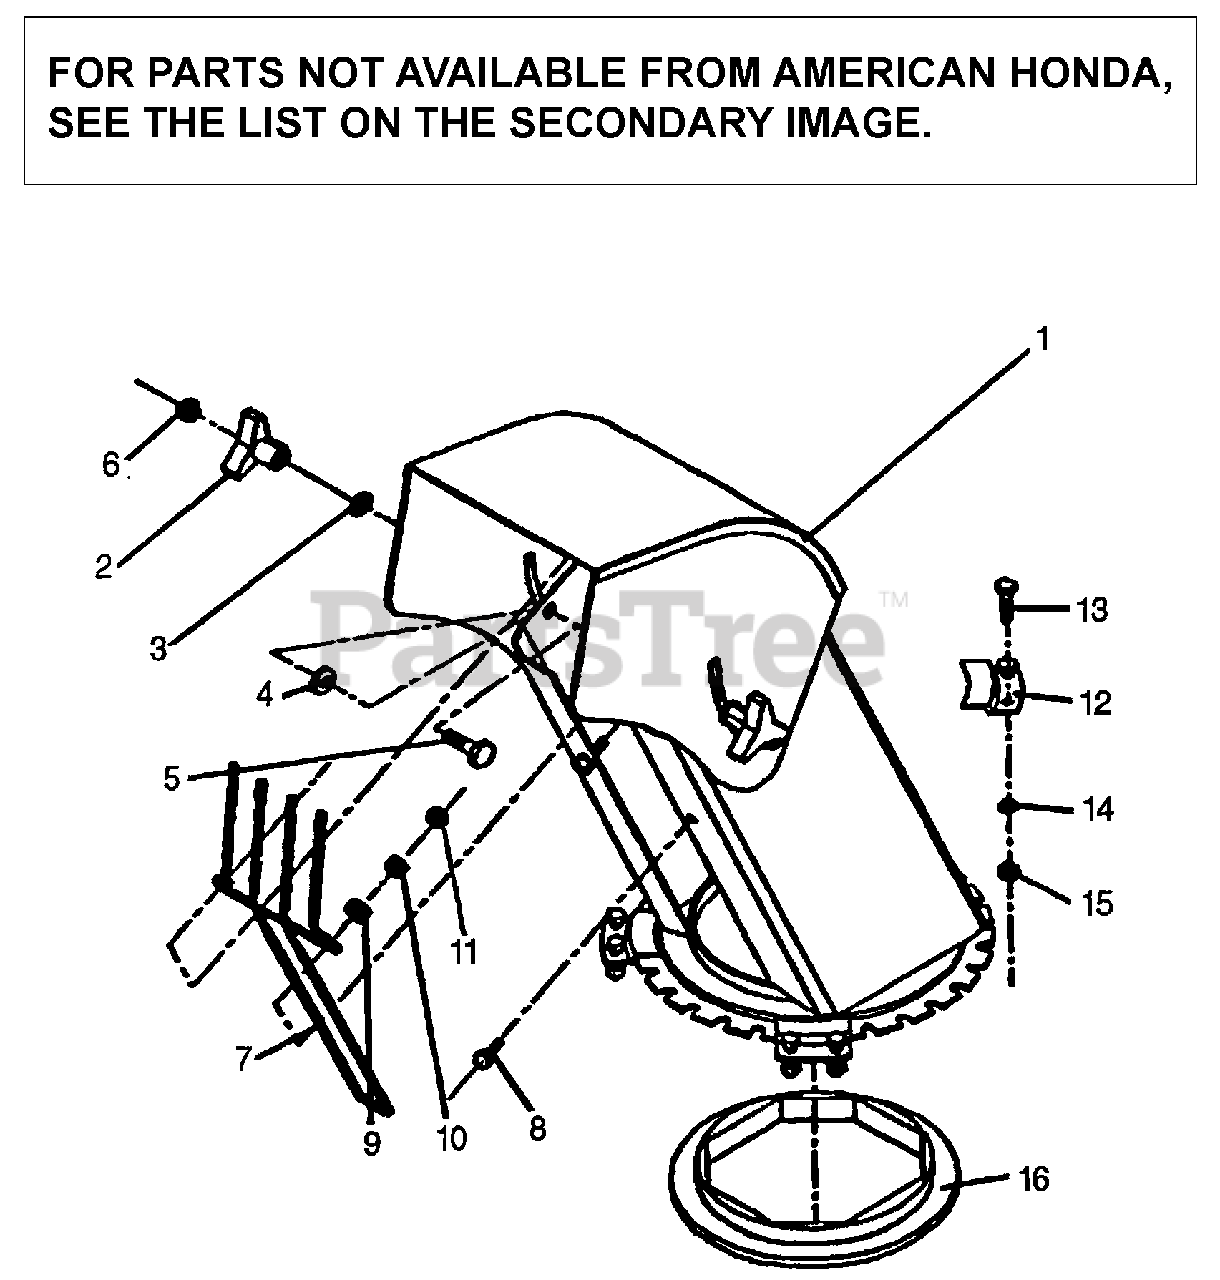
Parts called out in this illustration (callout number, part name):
1	CHUTE SUB-ASSY.
2	KNOB (5/16") (NC)
7	HAND GUARD
12	PLATE, RETAINING
16	CHUTE SUB-ASSY.
